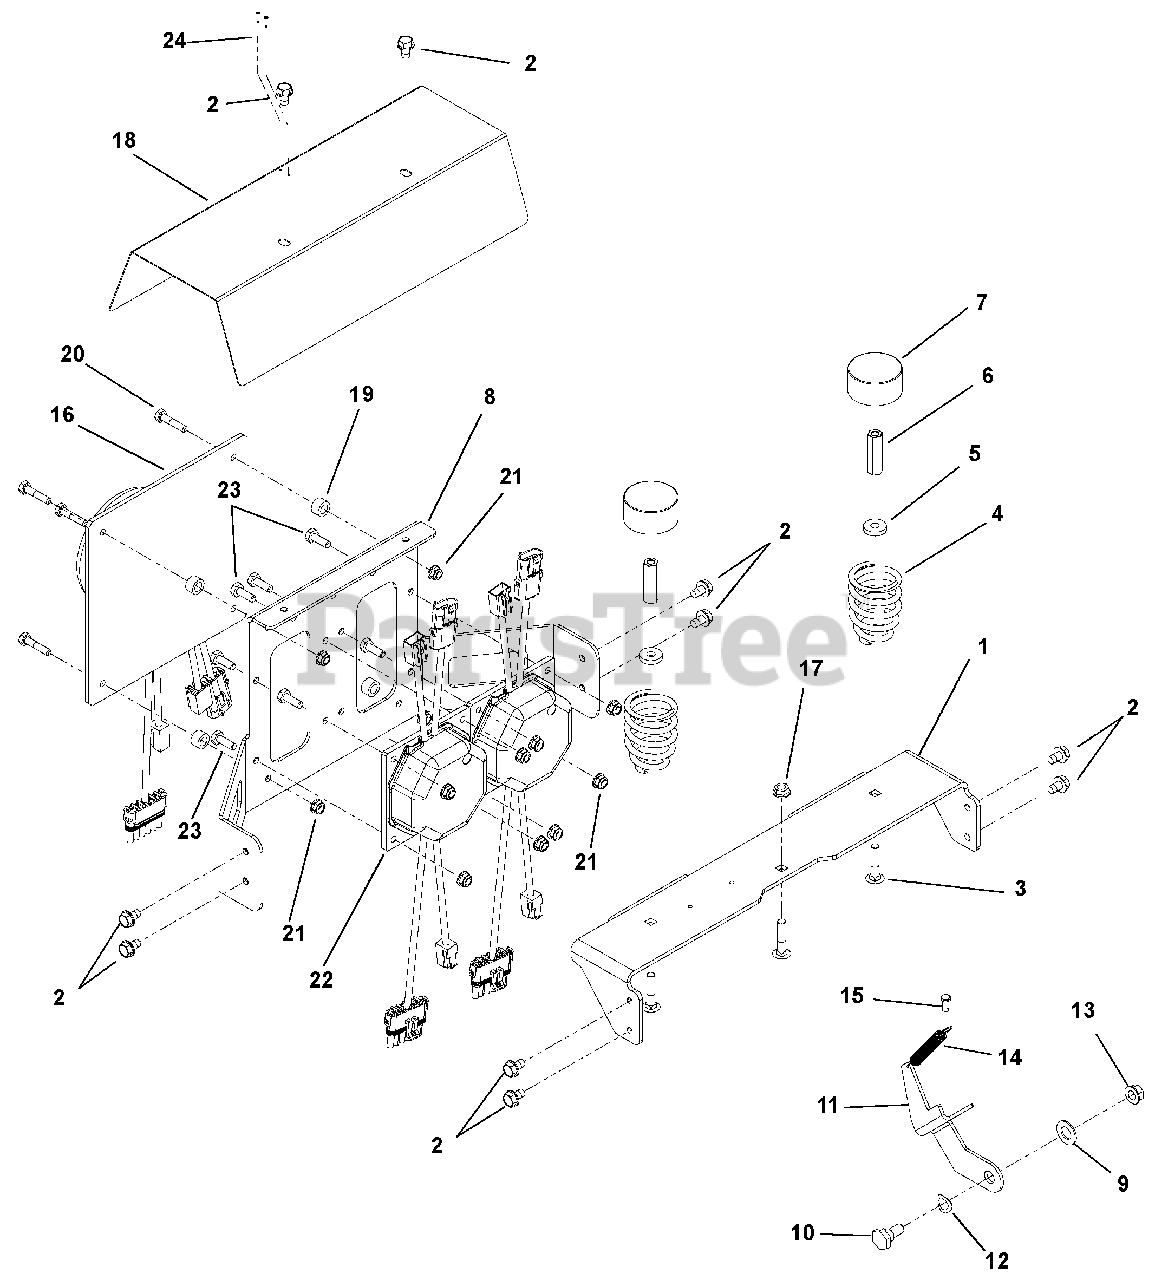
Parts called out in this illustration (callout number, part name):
1	BRKT, SEAT SPRING
2	@SCR-TAP .31-18X.50 HWH TR YWZ
3	@BLT-RDHDSQNK .31-18X1.50 G5YZ
4	SPRING, SEAT
5	WSHR-FL-STL .328X.87X.179 YWZC
6	NUT, COUPLING 5/16-18 X 1 3/4
7	HUB CAP
8	SUPPORT, CONTROLLER
9	WSHR-FL-STL.531X1.00X.063 YWZC
10	BLT,SHLDR EP .38-16X.30 HEX YZ
11	LATCH, SEAT
12	WSHR-WAVE .50X.75X.015 .13FRHT
13	@NUT-LK-TOP-FLG .38-16 YWZC
14	SG-TENS .035X.45X2.75 WLD 3.5
15	PIN-CLEV .250X.406
16	ASSY, DRIVE CONTROLLER
17	@NUT-LK-TOP-FLG .31-18 YWZC
18	SHIELD, WATER
19	BSHG-SLV .377X.624X.370
20	@BLT-HEX .25-20X1.25 GR5 YWZC
21	@NUT-LK-NYL-FLG .25-20 YWZC
22	ASSY-DECK MOTOR CONTROLLER
23	@BLT-HEX .25-20X.75 GR5 YWZC
24	SCR-TAP 6-32X.75 PH PAN HD
